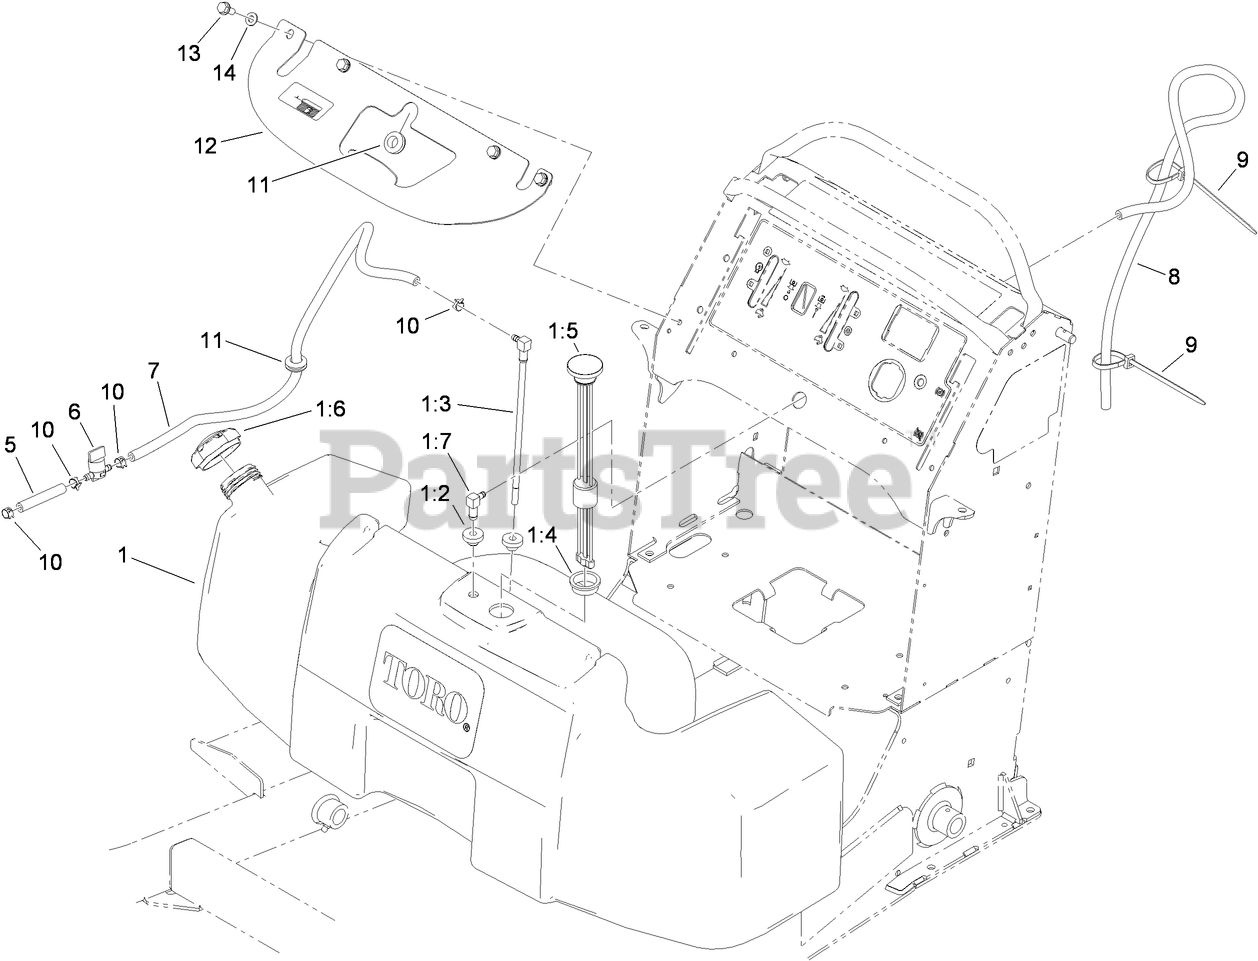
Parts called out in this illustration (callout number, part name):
1	TANK ASM
1:2	BUSHING
1:3	FITTING-FUEL, SCREEN TUBE
1:4	GROMMET
1:5	GUAGE-FUEL
1:6	CAP-FUEL
1:7	ELBOW-90 DEG
5	HOSE-FUEL
6	VALVE-FUEL
7	HOSE-FUEL
8	HOSE-FUEL
9	TIE-CABLE
10	CLAMP-HOSE
11	GROMMET
12	BRACKET-TANK
13	SCREW-HWHTF
14	WASHER-FLAT
